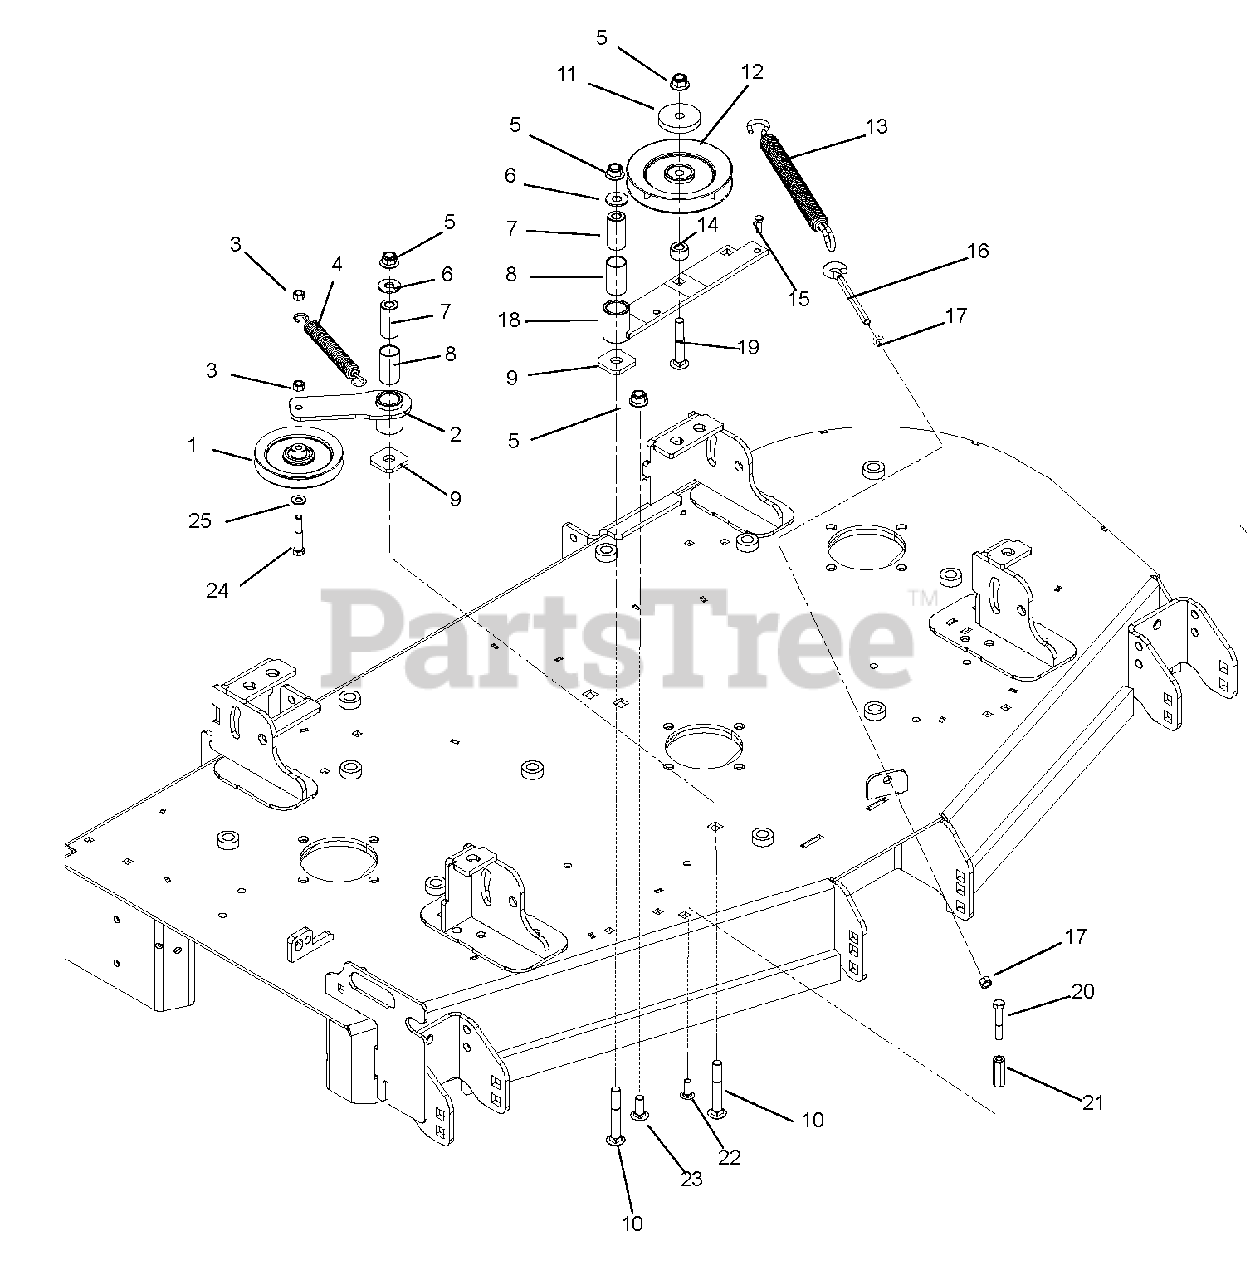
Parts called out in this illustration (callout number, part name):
1	V-Idler, 5.00"OD
2	Weldment, Idler Arm
3	Nut, Locking Center .38-16
4	Spring, Extension
5	Nut, Locking Nylon Flange .50-13
6	Washer, Flat Steel .563 x 1.38 x .109
7	Bushing, Spacer .505/.500 x .999/.996 x 2.05/2.03
8	Bushing 1.00 x 1.125 x 1.936
9	Washer, Flat .640 x 1.75 x .250
10	Bolt, Round Head Square Neck .50-13 x 3.50 Grade 5
11	Cap, Idler Bearing Sealing
12	Sheave, .50" ID x 6.00" OD V-Idler
13	Spring, Extension
14	Bushing, Spacer .502 x .997 x .50
15	Bolt, Shoulder EP .38-16 x .30 Hex
16	Bolt, .38-16 x 5.50 .62 Diameter Eye
17	Nut, Hex Jam .375-16
18	Weldment, Idler Arm
19	Bolt, Round Head Square Neck .50-13 x 3.00 Grade 5
20	Bolt, Hex .38-16 x 1.75 Grade 5
21	Nut, Cupling .375-16 x 1.75
22	Bolt, Round Head Square Neck .38-16 x 1.00
23	Bolt, Round Head Square Neck .50-13 x 1.50 FULL Thread Grade 5
24	Bolt, Hex .38-16 x 2.25 Grade 5
25	Washer, Flat Steel .406 x .812 x .065
